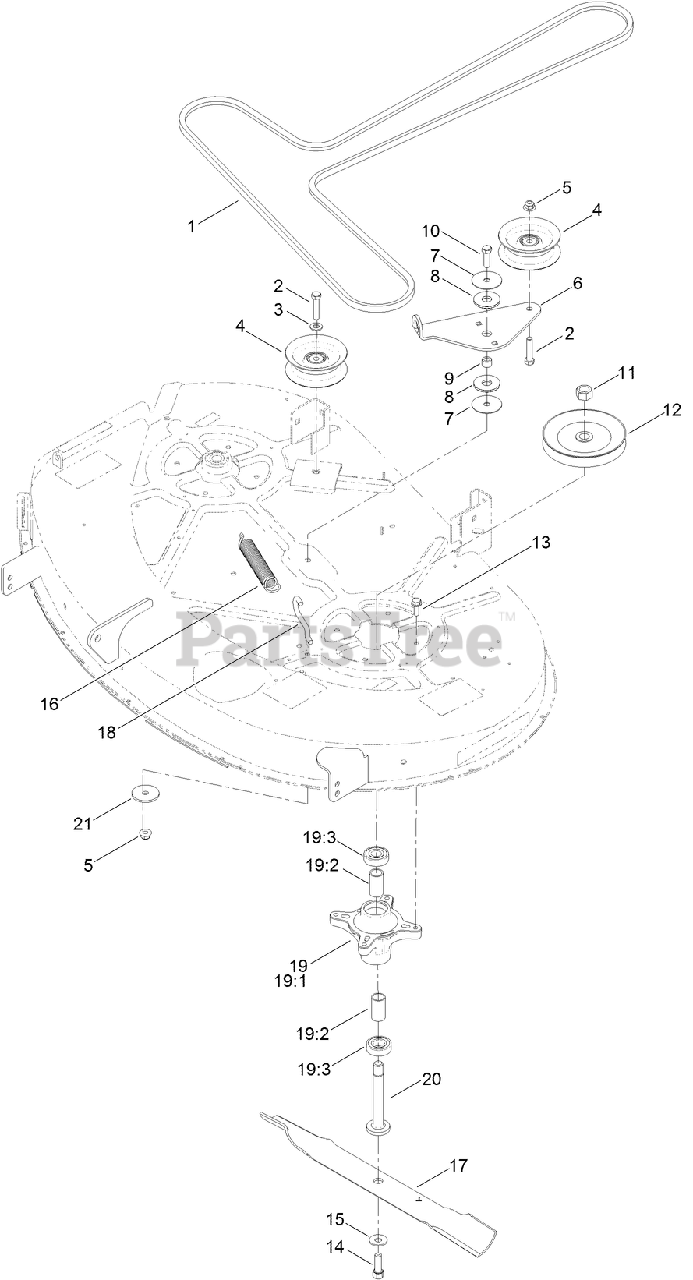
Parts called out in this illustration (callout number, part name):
1	V-BELT
2	SCREW-HH
3	WASHER-FLAT
5	NUT-HF, NI
6	ARM-IDLER
7	WASHER
8	WASHER-FRICTION, COMPOSITE
9	SPACER
10	SCREW-HH
11	NUT-HEX
12	PULLEY
13	SCREW-TAPTITE
14	SCREW-HH
15	WASHER-BELLEVILLE
16	SPRING-EXTENSION
17	BLADE-HIGH LIFT
18	HOOK-RETURN, SPRING
19	SPINDLE ASM
19:2	SPACER
20	SHAFT-SPINDLE
21	WASHER-REBOUND
